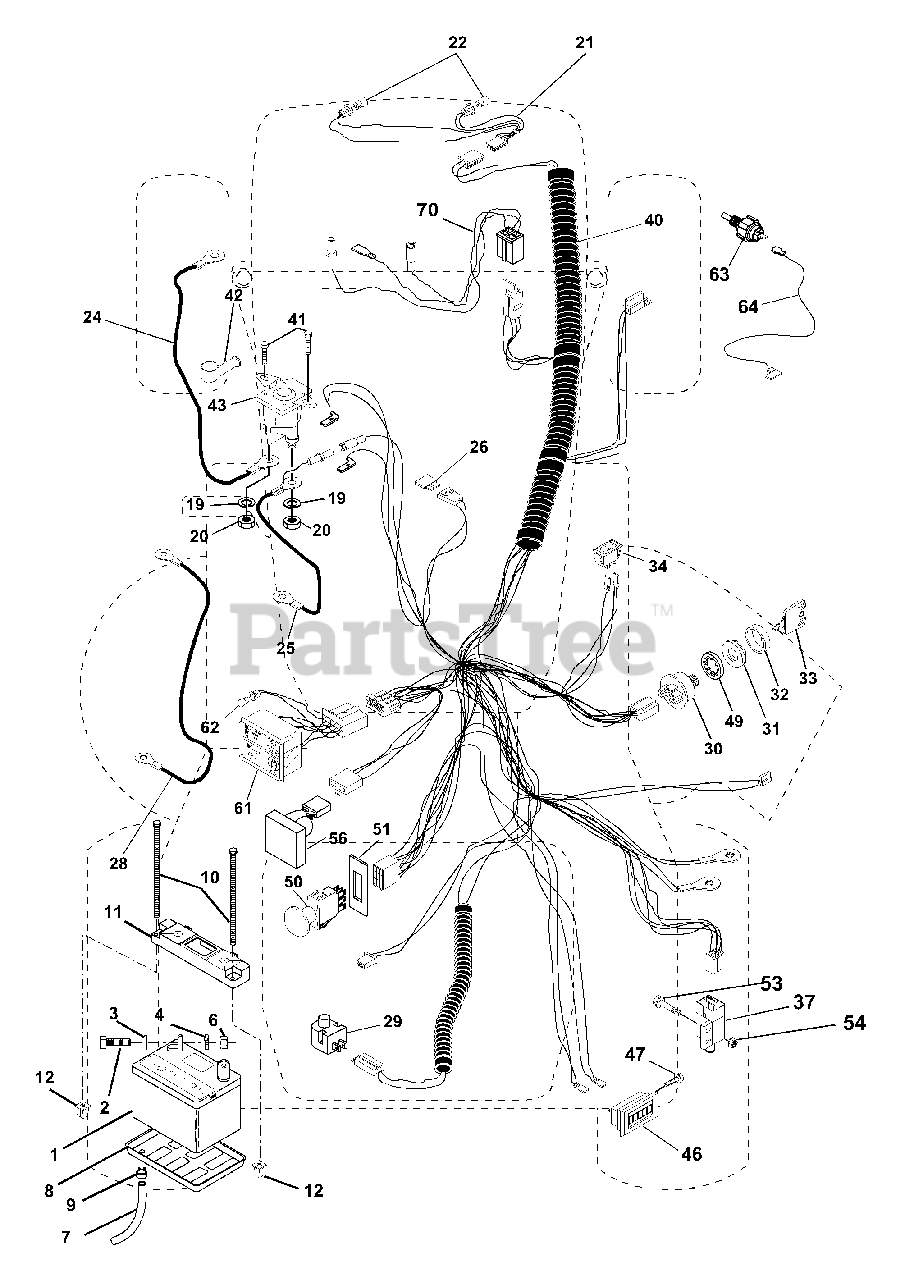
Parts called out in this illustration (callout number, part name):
1	Battery
2	Bolt Hex Head 1/4-20 x 3/4
3	Washer, Lock 1/4
4	Washer 9/32 x 5/8 x 16 Ga
6	Nut Fin Hex 1/4-20
7	Tube Plastic
8	Tray, Battery
9	Clamp, Hose
10	Bolt, Battery Frt 1/4-20 x 7.5 Zinc
11	Holddown Battery Dash Mount
12	Nut, Push Nylon 1/4" Battery
19	Washer, Lock 1/4
20	Nut, Jam Hex 1/4-20
21	Harness Socket Light W/4152J
22	Bulb Light
24	Cable, Starter
25	Cable, Battery
28	Cable, Ground
29	Switch, Plunger
30	Switch, Ign
31	Nut, Ignition Switch
32	Cover Switch Key
34	Switch, Light
37	Intlk Switch
40	Harness Ign.
41	Screw 1/4-20 x 1/2
42	Cover, Terminal Red
43	Solenoid
46	Meter Hour
47	Screw #10-24 x 1/2
49	Washer, Lock Internal Tooth 5/8
50	Switch, PTO
51	Ring Retainer PTO
53	Screw Hex Washer Hd #10-32 x 1
54	Nut Keps #10-32
56	Sensor Lo-Volt
61	Light Pkg Asm
62	Bulb, Light Pkg.
63	Switch Engine Oil Pressure
64	Wire, Lead Sentry Oil Vanguard
70	harness Engine Vanguard II VGT
